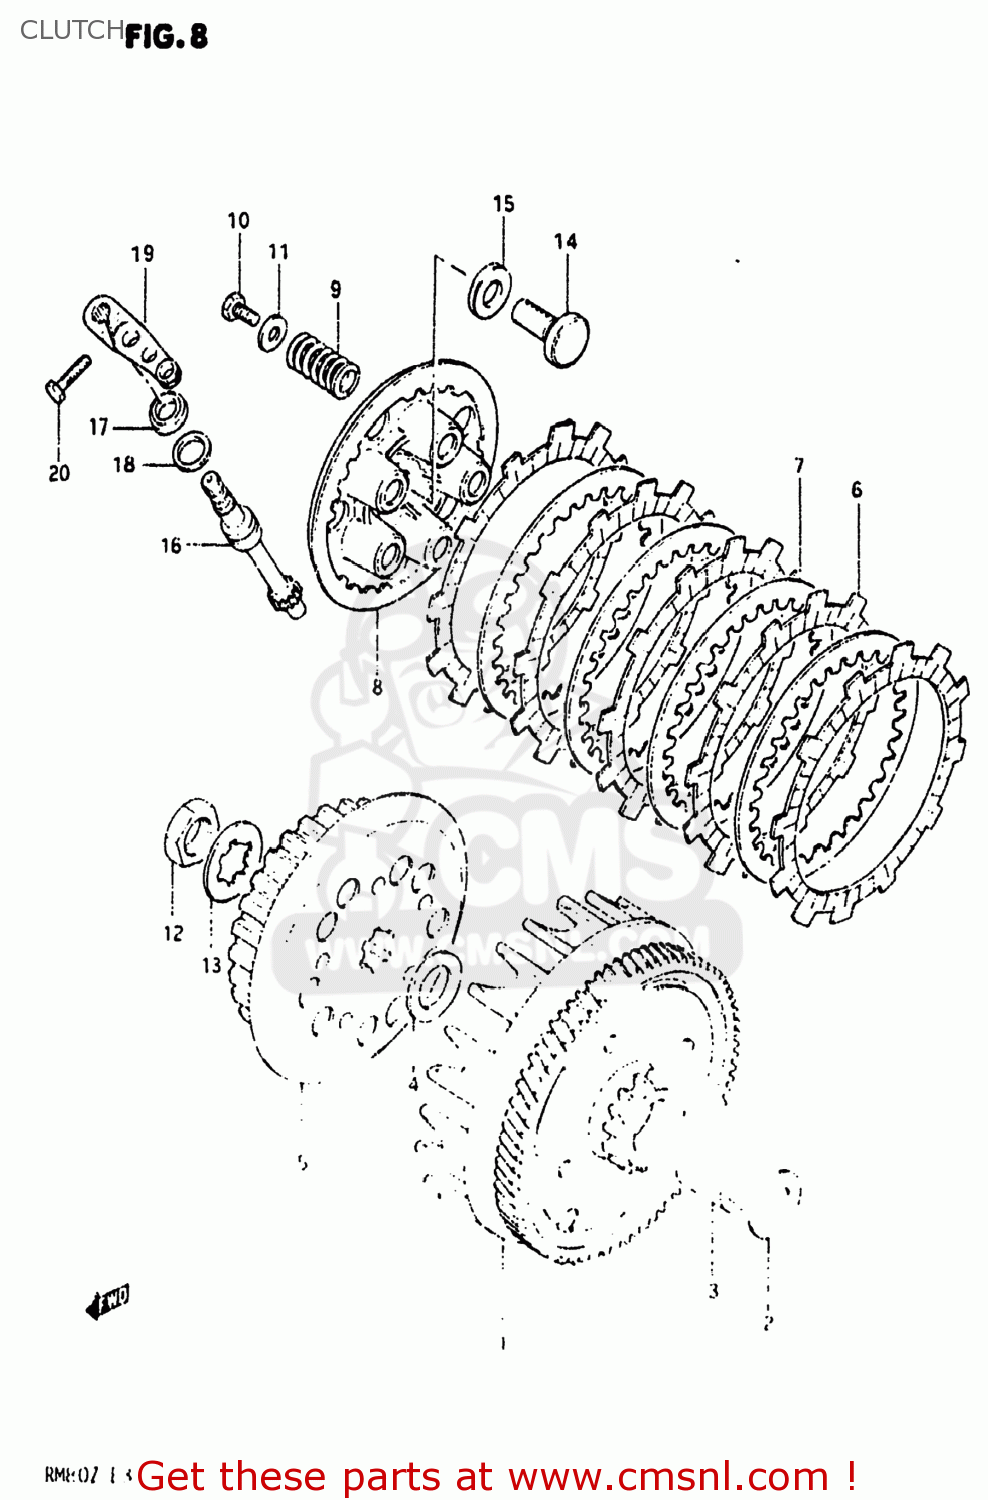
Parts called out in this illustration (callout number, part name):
1	GEAR ASSEMBLY,PRIMARY DRIVE
2	WASHER,THRUST
3	SPACER(17X22X28.5)
4	WASHER
5	HUB,CLUTCH SLEEVE
6	PLATE,CLUTCH DRIVE
7	PLATE,CLUTCH DRIVEN
8	DISC,CLUTCH PRESSURE
9	SPRING
10	BOLT(5X16)
11	WASHER (5.5X16X1.2)
12	NUT
13	WASHER,LOCK
14	RACK,CLUTCH RELEASE
15	BEARING(10X22X2.8)
16	PINION,CLUTCH RELEASE
17	OIL SEAL
18	WASHER (12X17X1)
19	ARM,CLUTCH RELEASE
20	BOLT, UPPER
